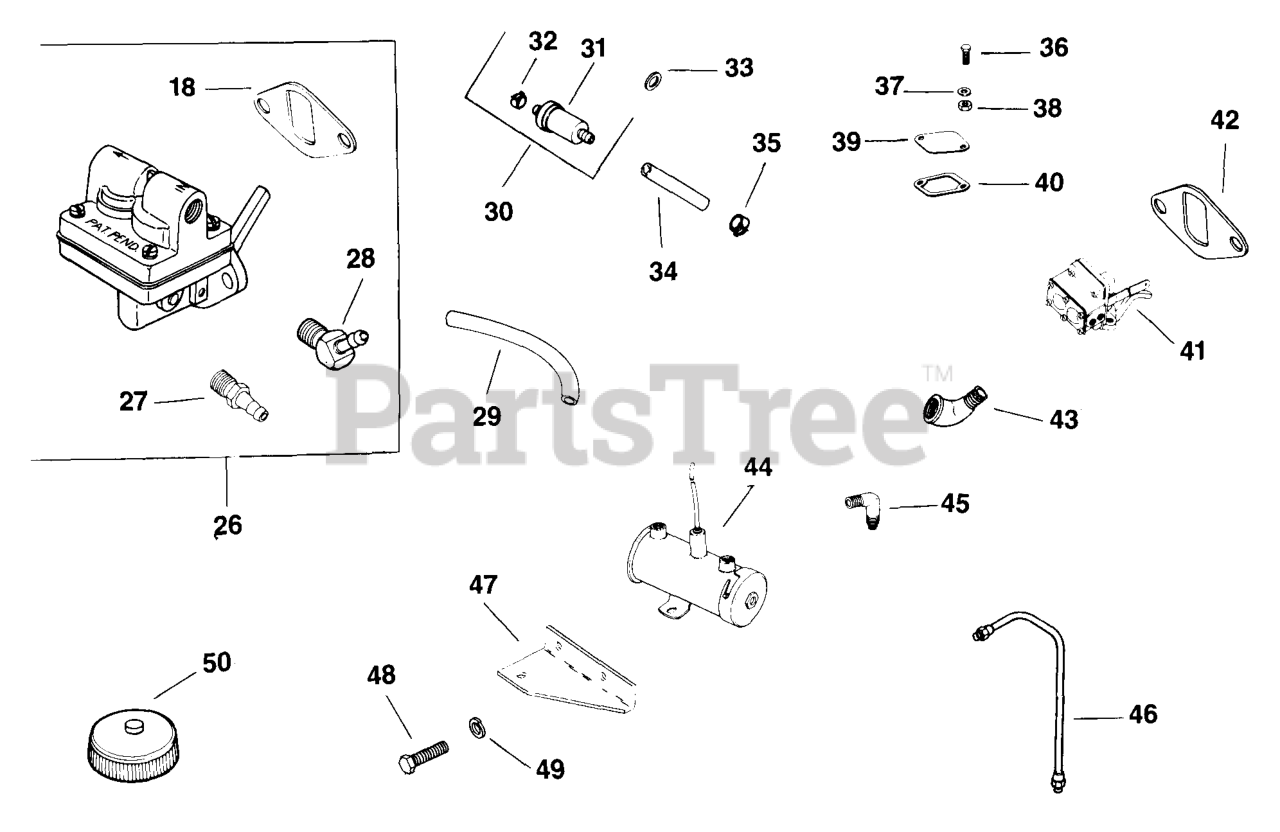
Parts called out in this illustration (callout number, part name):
27	CONNECTOR, 45 DEG.
28	CONNECTOR USE 25 326 03-S
29	LINE, FLEXIBLE FUEL - DISCONTINUED
30	KIT, FUEL FILTER - DISCONTINUED
31	FUEL FILTER - USE 25 050 03
34	LINE - DISCONTINUED
35	CLAMP, HOSE
